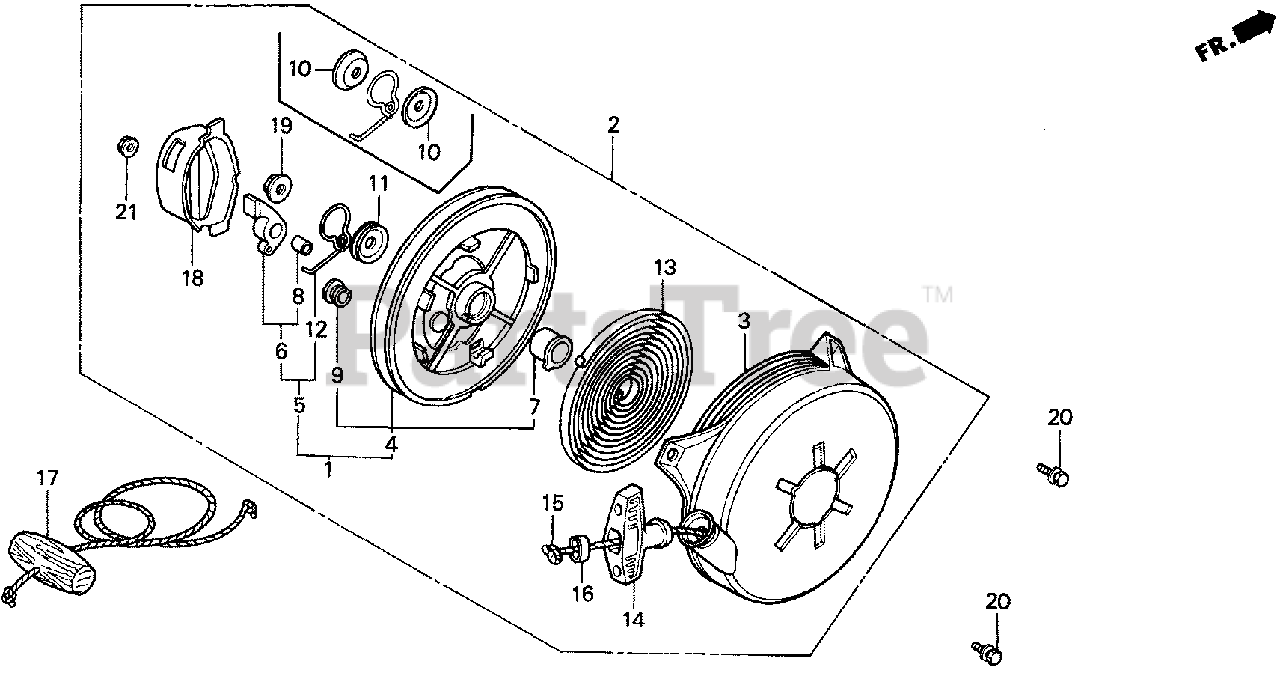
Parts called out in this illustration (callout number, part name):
1	REEL, STARTER
2	STARTER ASSY., RECOIL *R8* (BRIGHT RED)
3	CASE, STARTER *R8* (BRIGHT RED)
4	REEL, STARTER
7	BOSS, REEL
8	BUSH, RATCHET
9	BUSH, REEL STARTER
10	PLATE, FRICTION
11	PLATE, FRICTION
12	SPRING, FRICTION
13	SPRING, RETURN
14	GRIP, STARTER
15	ROPE, RECOIL STARTER (#5X55")
16	SUPPORT, GRIP
17	ROPE, STARTER (#5X55") Use from Engine SN 1779881.
18	COVER, REEL STARTER
19	NUT, SELF-LOCK (8MM)
20	BOLT, FLANGE (6X8)
21	NUT, FLANGE (5MM)
